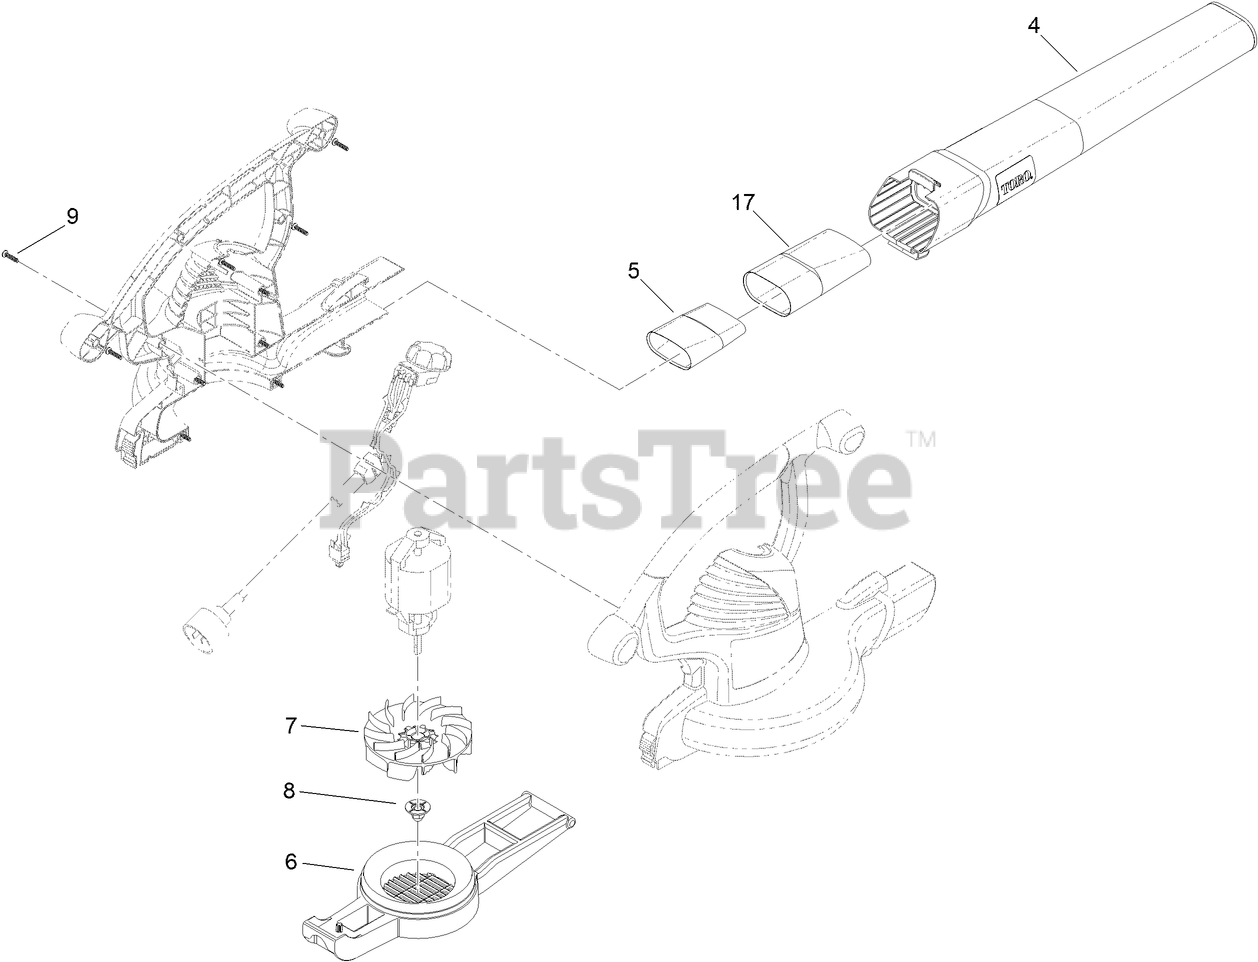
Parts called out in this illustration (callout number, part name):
4	TUBE-BLOWER
5	TUBE-INSERT, SUPER
6	COVER-INLET
7	IMPELLER-PLASTIC
8	NUT-IMPELLER
9	SCREW-PPH
17	TUBE-INSERT
